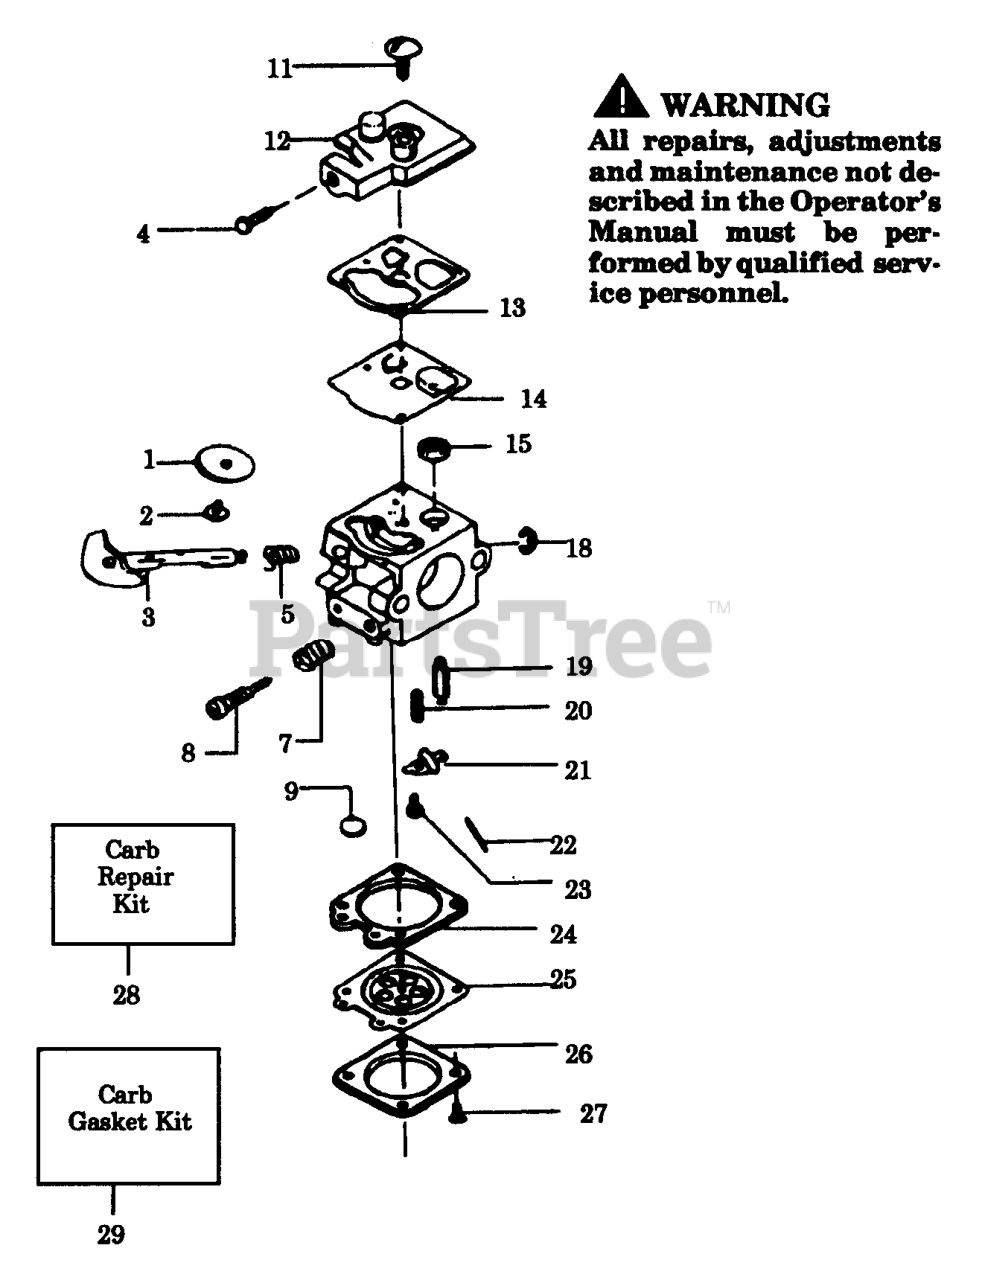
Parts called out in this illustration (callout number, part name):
1	THROTTLE VALVE 22B
2	SCREW SHUTTERS
3	Shaft Ass'y.-Throttle
4	SCREW IDLE ADJUSTMENT
5	Spring-Throttle Return
7	SPRING,HI-SPD NDL 22B
8	Needle-High Speed Mixture
9	Plug-5/16 Dia. Welch
11	SCREW PUMP COVER
12	COVER-PUMP/22B
13	GASKET-FUEL PUMP
14	DIAP FUEL PUMP
15	SCREEN-DUTCH TWILL INLE
18	Ring-Throttle Retainer
19	INLET NEEDLEVALVE
20	SPRING, MOTOR LEVER
21	LEVER
22	PIN
24	GASKET-METER DIAP
25	DIAPHRAGM
26	COVER MOTOR DIAPHRAGM
27	SCREW, MOTOR COVER
28	CARB. REPAIR KIT 22B
29	CARB GSKT KIT 22B
